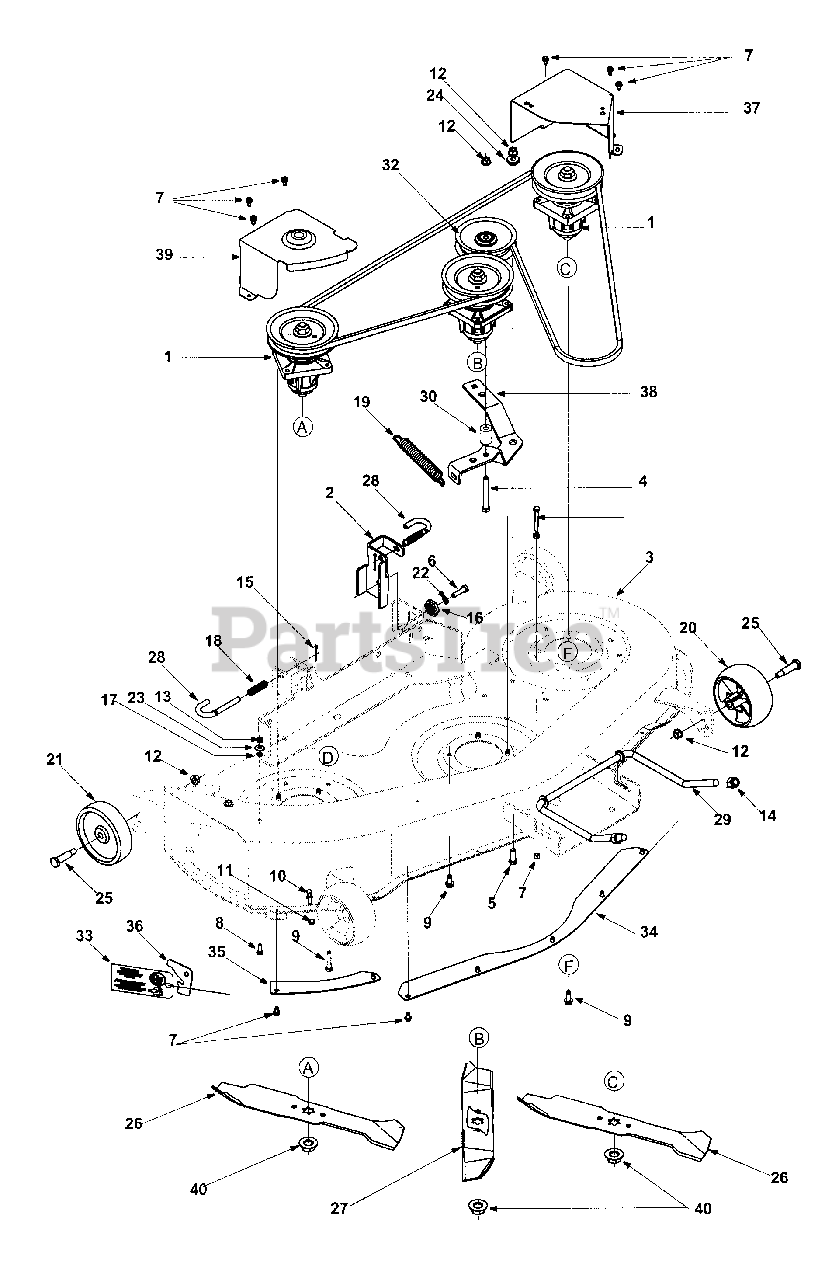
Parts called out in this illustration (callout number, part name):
1	Spindle Assembly: Single
5	Hex Bolt 3/8-16 x 1.0,GR5
6	Hex Bolt 5/16-18 x 1.25
7	TT Screw 1/4-20 x 0.5
8	Hex Bolt 1/4-20 x 0.620
9	LD Screw 5/16-18 x 0.75
10	Grasscatcher Pin
11	Hex Lock Nut 1/4-20
12	Flange Lock Nut 3/8-16
13	Hex Nut 1/4-20
14	Hex Lock Nut 1/2-13
15	Cotter Pin
16	Gear: Deck Adjustment
18	Compression Spring
19	Extension Spring
20	Deck Wheel 5.0 dia Ball
21	Deck Wheel 5.0 x 1.38
22	Lock Washer
23	Bell Washer
24	Shoulder Spacer
25	Shoulder Screw
26	Blade 16.28
27	Blade 14.88
28	Rod: Deck Release Handle
29	Deck Rod: Front Adjustment
31	V- Belt
32	Idler Pulley
33	Danger Tag
34	Deck Skirt: Center
35	Deck Skirt RH
36	Chute Stop
